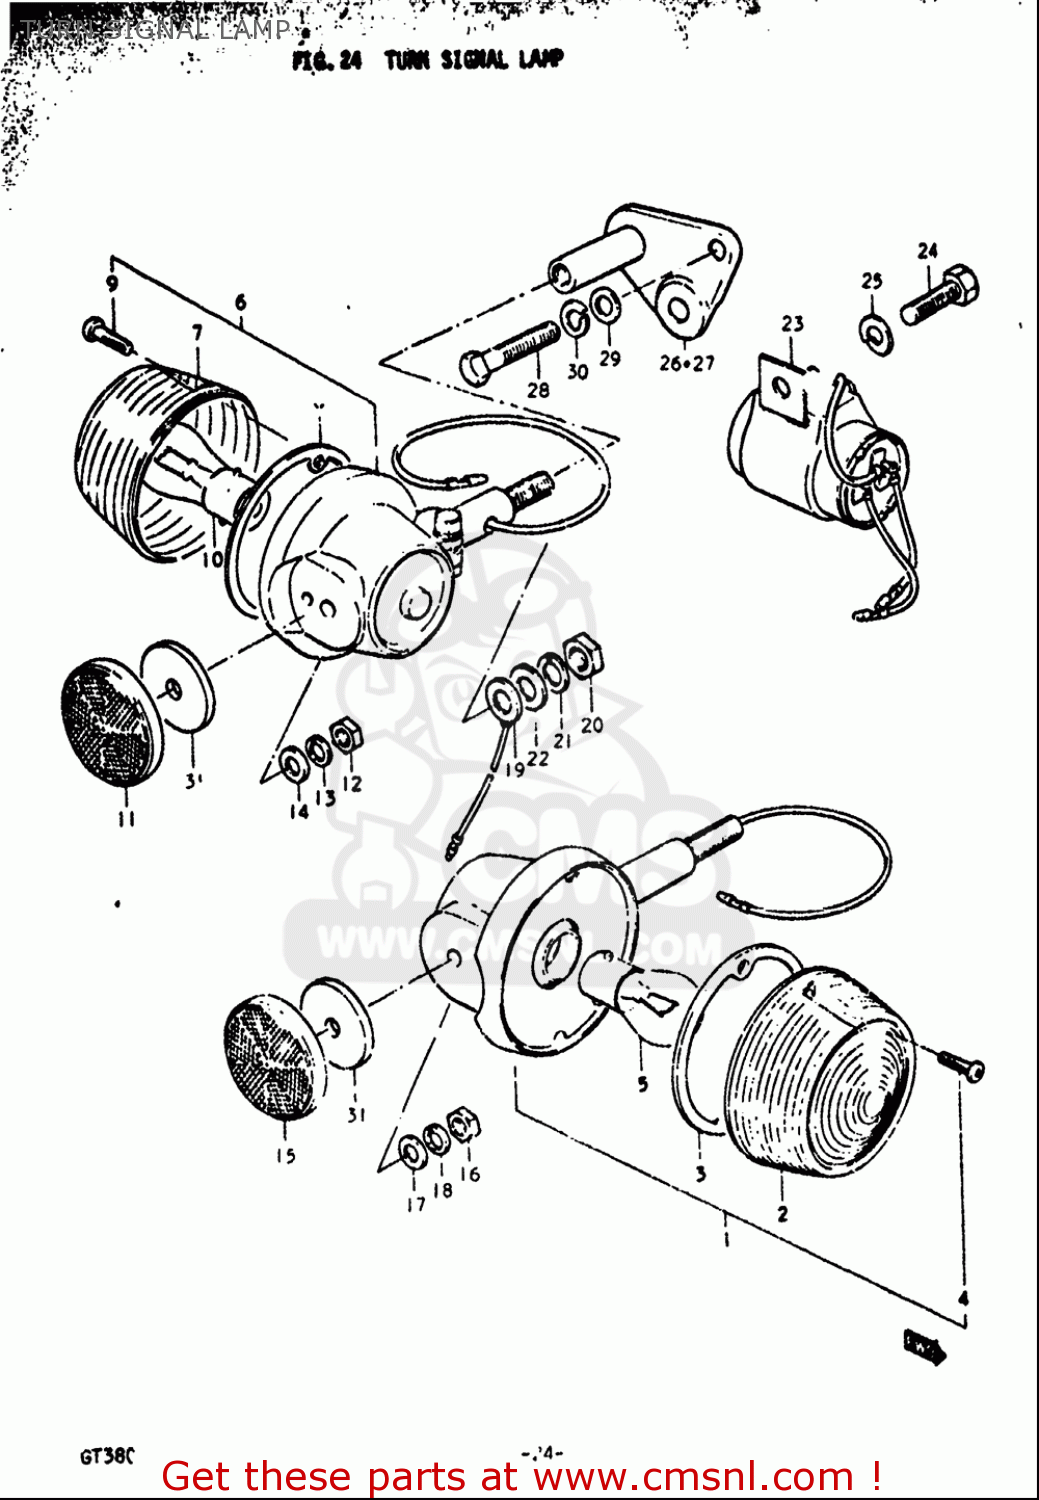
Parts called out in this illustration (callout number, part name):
2	LENS
3	GASKET,TURNSIGNAL LENS (NAS)
4	SCREW
5	BULB(12V23W,STANLEY,A4577A)
8	GASKET,TURNSIGNAL LENS (NAS)
9	SCREW
10	BULB(12V23W,STANLEY,A4577A)
12	NUT
13	WASHER(5.5X18X1)
14	WASHER,LOCK
15	REFLEX REFLECTOR,RR
16	NUT
17	WASHER(5.5X18X1)
18	WASHER,LOCK
19	LEAD WIRE,EARTH
20	NUT
21	WASHER,LOCK
22	WASHER
23	RELAY,TURN SIGNAL
24	BOLT
25	WASHER,LOCK
26	BRACKET, REAR TURN SIGNAL RH
28	BOLT
29	WASHER
30	WASHER,LOCK
